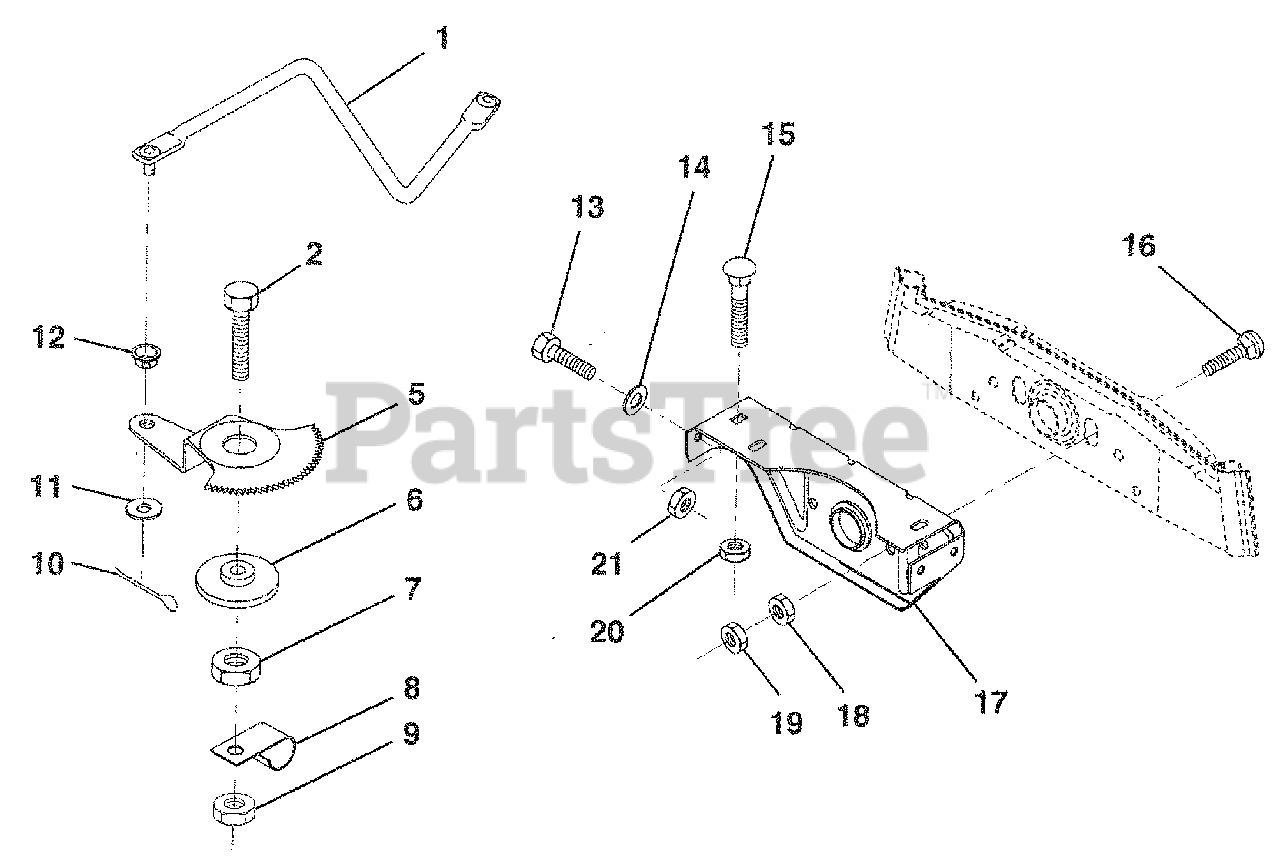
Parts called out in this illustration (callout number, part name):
1	Link, Drag
2	Bolt, Fin Hex 1/2-13 x 1-3/4
5	Gear, Sector
7	Nut, Heavy Hex Top Lock 1/2- 13 UNC
8	Clip, insulated
9	Nut, Crownlock 3/8-16
10	Pin. Cotter 1/8 x 3/4
11	Washer, 13/32 x 13/16 x 16 Ga.
13	Bolt, Hex Hd. 5/16-18 UNC x1
14	Washer 11/32 x 7/8 x 16 Ga.
15	Bolt, Carnage 3/8-16 UNC x 3/4
16	Bolt, Carriage
17	Support, Front Axle
18	Nut, Fin Hex 3/8-16 UNC
19	Nut, Centerlock 3/8-16 UNC
20	Nut, Crownlock 3/8-16 UNC
21	Nut, Crowniock 5/16-18
